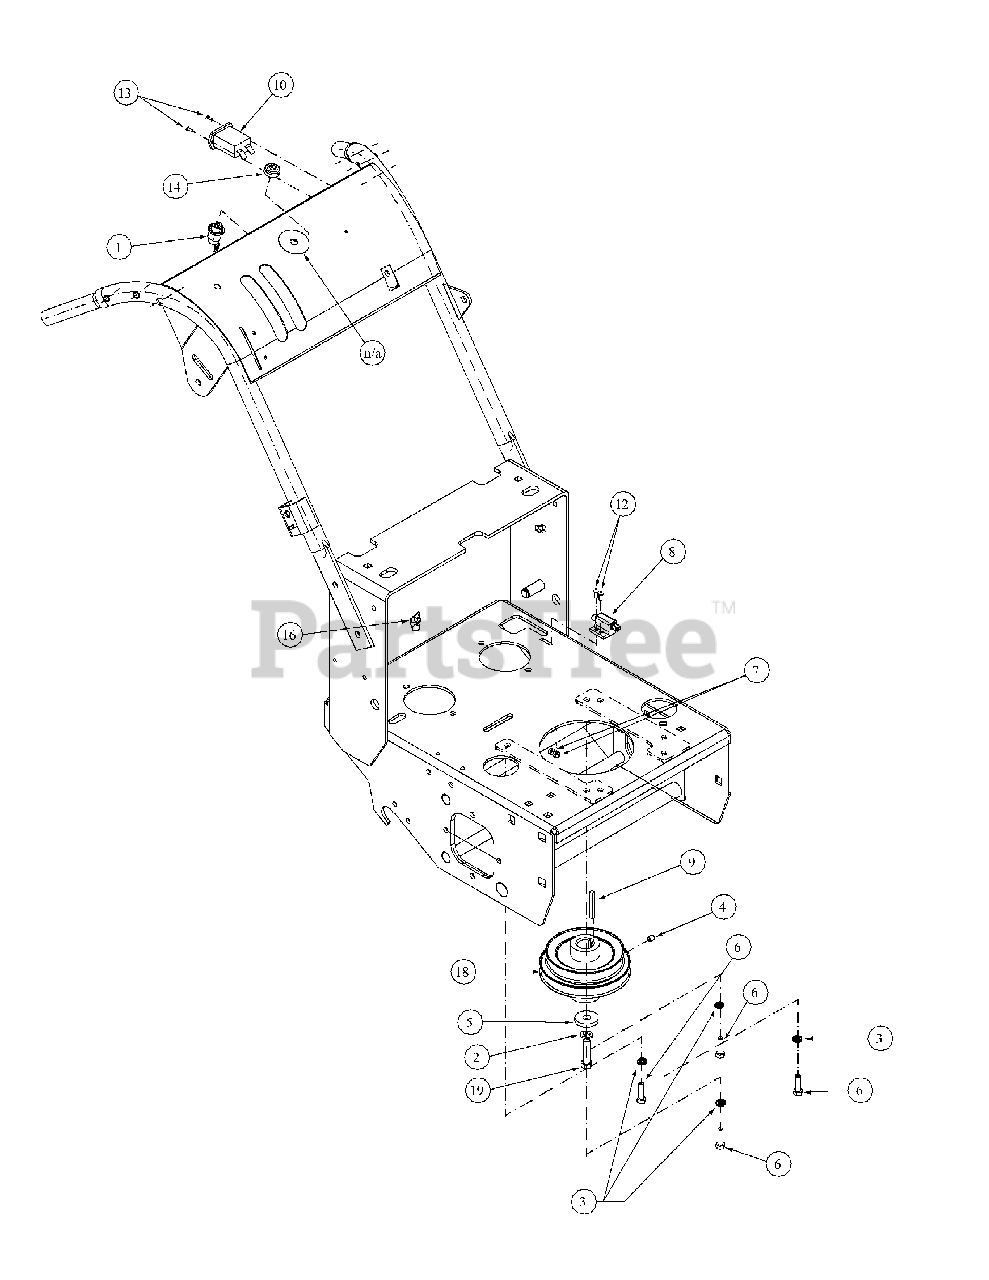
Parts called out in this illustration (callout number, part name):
1	On/Off Ignition Switch
2	Lock Washer, M10
3	Lock Washer, 5/16
4	Nylock Screw, 5/16-18 x 3/8
5	Clutch Washer
6	Capscrew, M8-1.25 x 30
7	Lock Nut, Nylon Insert, #10-32
8	Delta Switch
9	Key Stock, 1/4 x 1/4 x 2
10	Meter, Hour
10	Belt, Hydro Pump
12	Phil. He. Mach. Screw #10-32 x 5/8
13	Rivet
14	Nut w/Cap, 5/8-32 Ignition
14	Kawasaki 14 HP Engine
16	Support Clamp, 3/8 OD
16	Harness Wire
18	Double Pulley
19	Capscrew, M10-1.5 x 50mm
